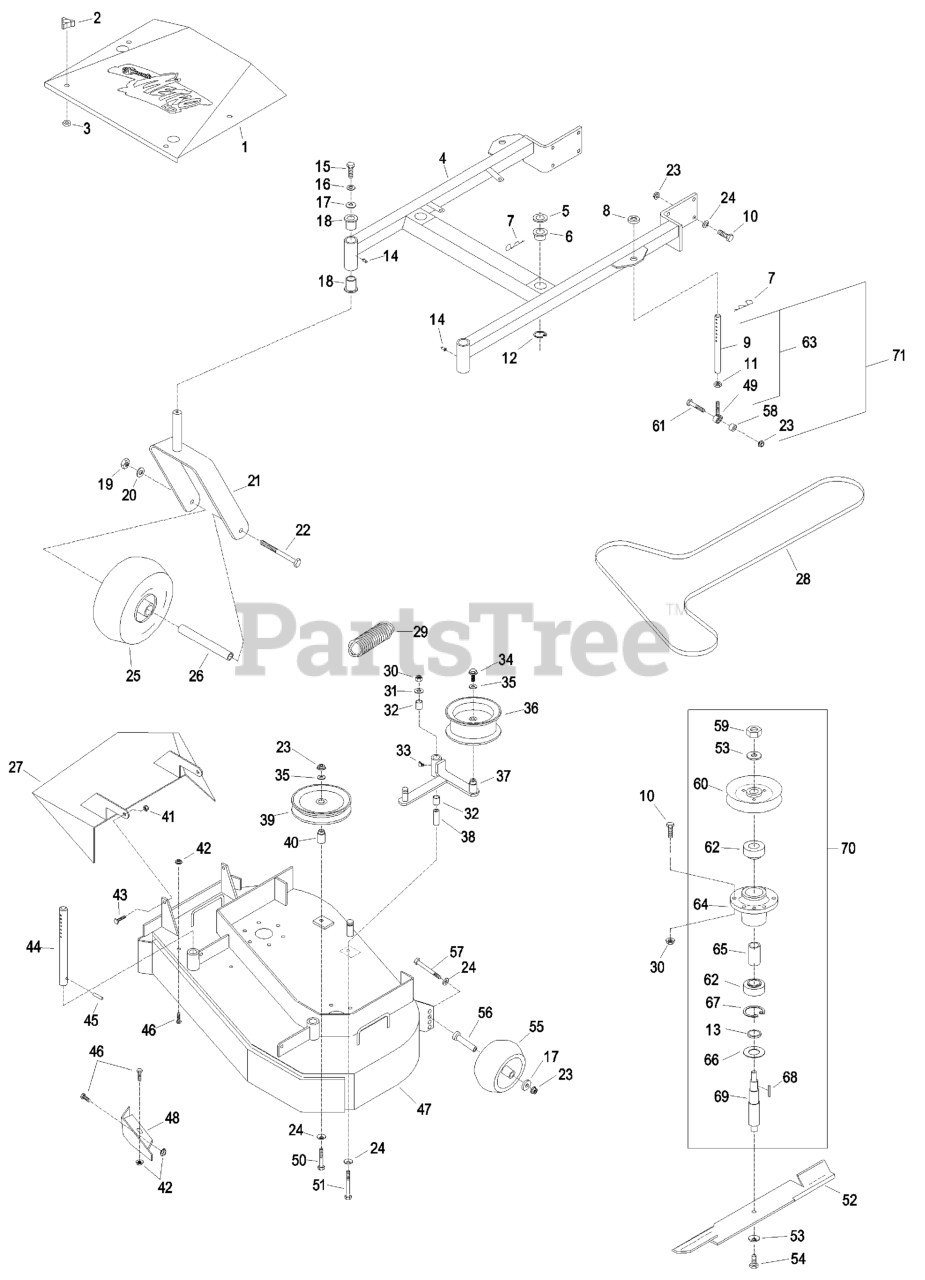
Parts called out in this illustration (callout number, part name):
1	SHIELD W/DECAL,MHP36
2	KNOB-3 PRONG
4	DECK SUPPORT W/BSHGS 36"
5	SPACER-DECK SUPPORT
6	BUSHING-DECK
7	PIN,HAIR COTTER
9	LINK,SUPPORT
13	SPACER-PULLEY/BEARING
18	BEARING-FLANGED
28	BELT,DECK DRIVE
32	SLEEVE-BEARING
38	BUSHING-PIVOT, IDLER
39	PULLEY-IDLER
40	BUSHING-IDLER
44	ROD,DECK SUPPORT
47	ASM,DECK W/DECALS TTHP/MH
49	BALLJOINT
51	SCREW-HH
53	WASHER-SPRING
55	ROLLER-SCALP, ANTI
56	BUSHING-ROLLER
60	SHEAVE,W/HUB 5.72
62	BEARING
65	SPACER-BEARING
66	GUARD-BEARING, BOTTOM
68	KEY-RECTANGLE
69	SHAFT,SPINDLE
70	HOUSING,CUTTER COMPLETE
